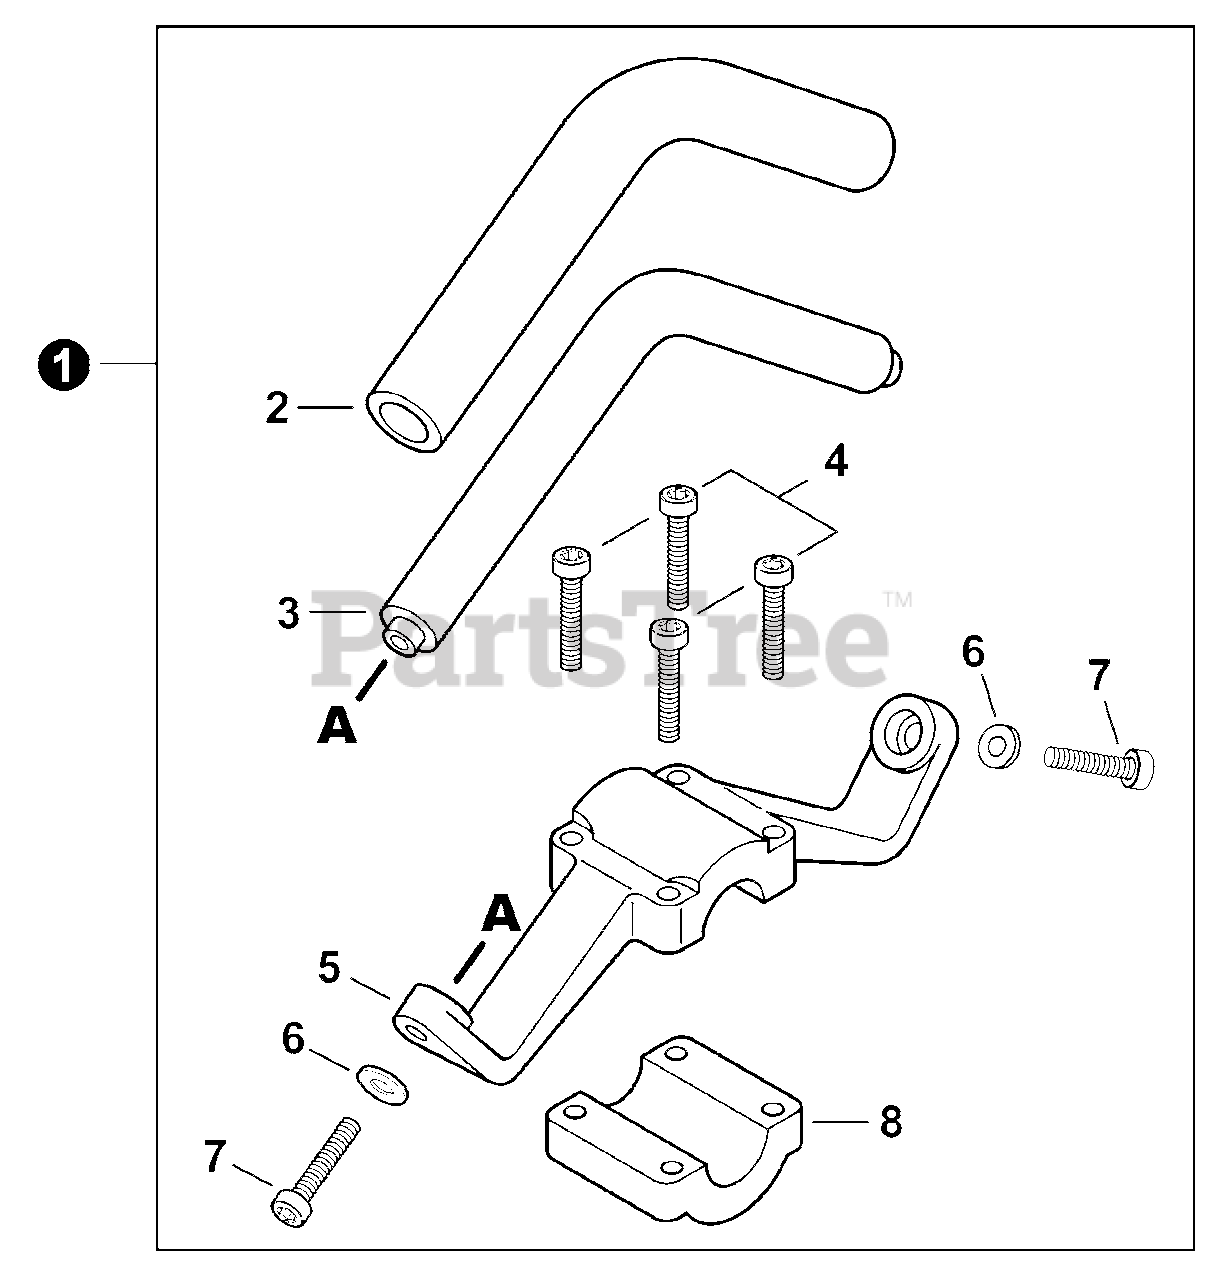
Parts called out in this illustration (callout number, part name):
1	HANDLE ASSY, SUPPORT
2	GRIP, HANDLE
3	HANDLE, SUPPORT
4	BOLT, TORX 5x30
5	BRACKET, HANDLE
6	WASHER, FLAT 5.5x10x0.8
7	BOLT, TORX 5x20
8	BRACKET, HANDLE
